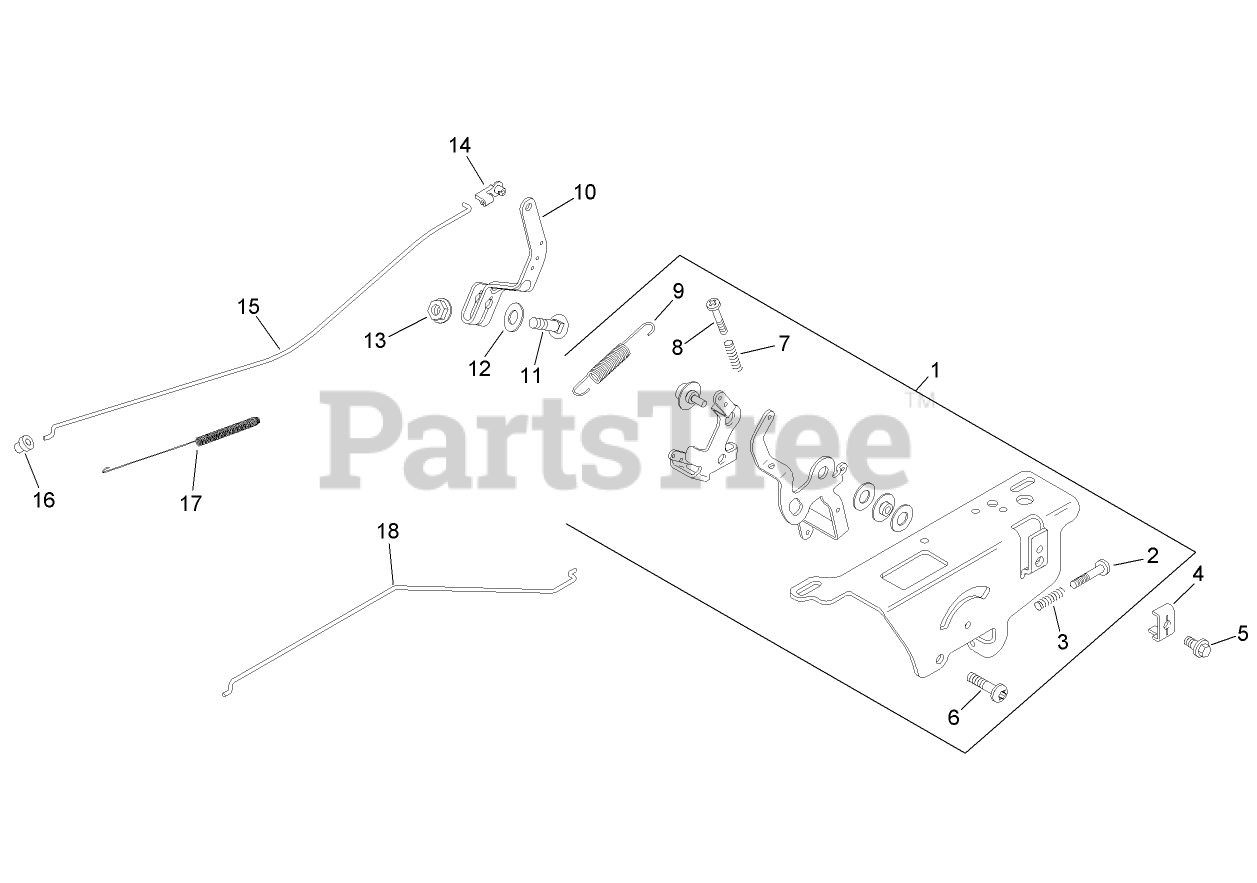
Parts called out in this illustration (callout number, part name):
1	Speed Control ASM
2	Screw-Thread Forming (M4x0.7x25)
2	SCREW-PHL THD FRM (M4X0.7X38)
3	Spring-Control, Speed
3	SPRING-CONTROL, SPEED (LONG)
4	CLAMP-CABLE
5	SCREW-FLANGE, THREAD FORMING (M5X0.8X16)
6	Screw-Socket, 6 Lobed (Thread Forming, M6x1.0x20)
7	Screw-Thread Forming (M4x0.7x25)
8	SCREW-PHL THD FRM (M4X0.7X38)
9	Spring-Governor
10	Lever-Governor
11	Bolt-Square Neck, Round Head (1/4-20x1)
12	Washer-Lock, Internal Tooth (1/4)
13	Nut-Flange, Hex (1/4-20)
14	BUSHING-RETAINING, LINKAGE
15	Linkage-Throttle
16	BUSHING-LINKAGE, THROTTLE
17	Spring-Linkage
18	Linkage-Choke (Single Wire)
